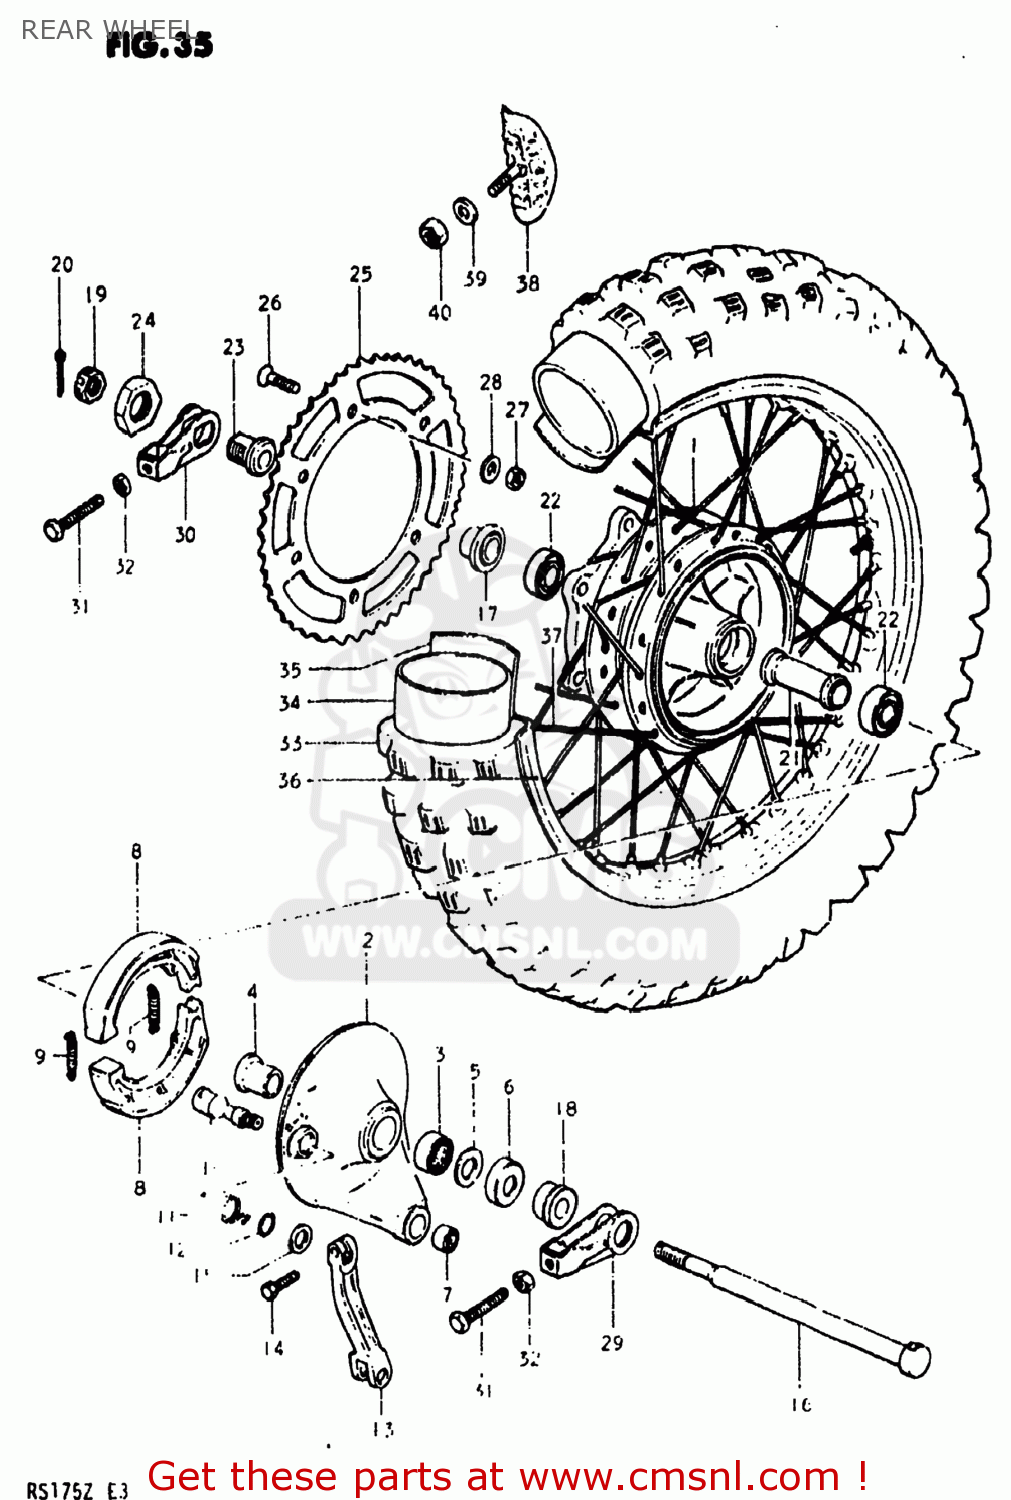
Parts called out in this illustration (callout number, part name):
1	DRUM,REAR HUB
2	PANEL SET,REAR HUB
3	BEARING(22X29X25)
4	SPACER,REAR HUB PANEL
5	WASHER
6	COVER, PANEL DUST SEAL
7	SPHERICAL BEARING,TORQUE
8	SHOE,BRAKE
9	SPRING(L:34)
10	CAM,FR BRAKE
11	SPRING
12	O RING(D:2.5,ID:11.4)
13	LEVER,RR BRAKE CAM
14	BOLT
15	WASHER(12.5X20X1)
16	AXLE,REAR
17	SPACER,RR AXLE,L
18	SPACER (15.2X26X34)
19	NUT 12MM
20	COTTER PIN
21	SPACER,REAR HUB BEARING
22	BEARING
23	SPACER,CHAIN ADJUSTER,L
24	NUT
25	SPROCKET,REAR (NT:46)(AL)
26	SCREW(8X33.5)
27	NUT
28	WASHER
29	ADJUSTER,CHAIN
30	ADJUSTER,CHAIN,L
31	BOLT
32	NUT
33	TIRE
34	TUBE ASSEMBLY,WHEEL,INNER
35	PROTECTOR,INNER TUBE
36	RIM,REAR WHEEL
37	SPOKE SET,REAR
38	STOPPER,BEAD
39	WASHER
40	NUT
